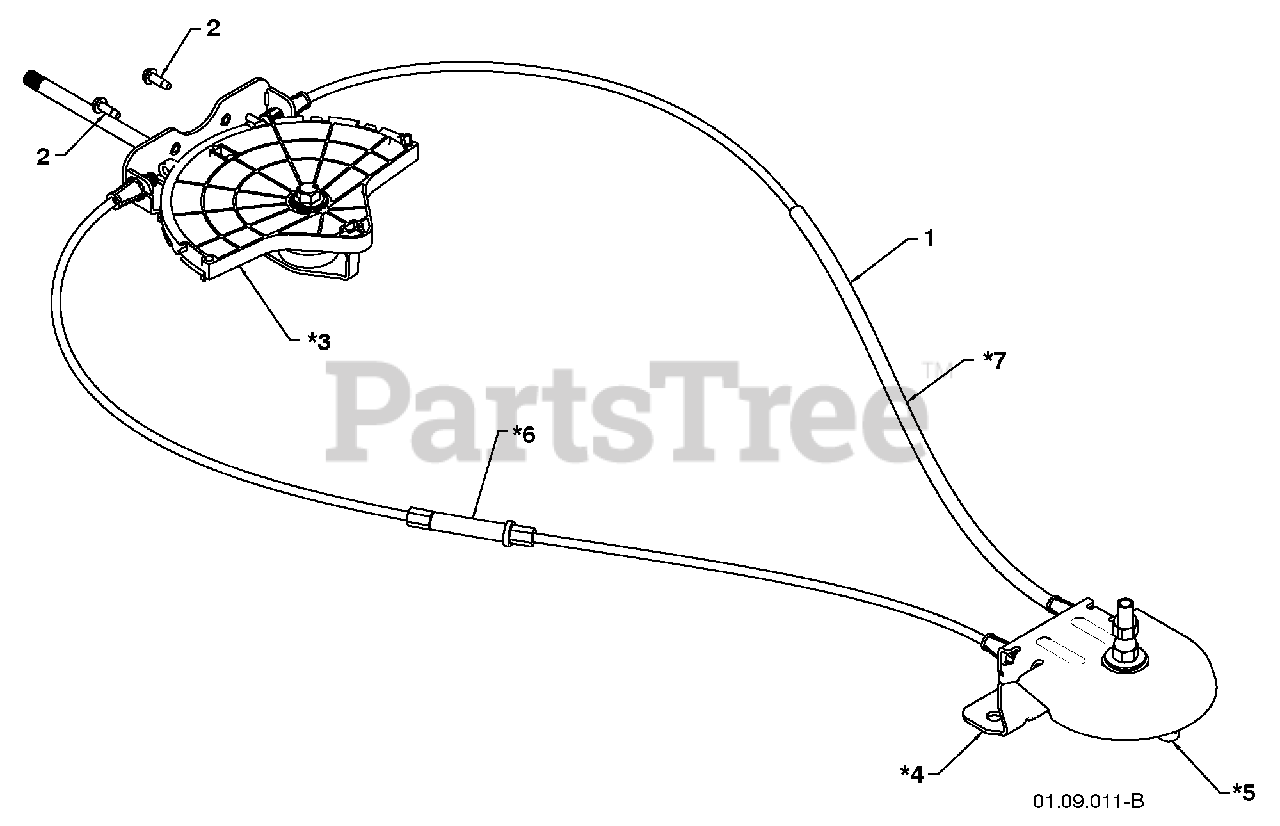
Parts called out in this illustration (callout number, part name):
1	LEVER/CABLE ROTATOR ASSEMBLY
2	SCREW 10-24 X .625
3	ROTATOR HEAD
4	ROTATOR PIVOT BRACKET
5	PULLEY PIVOT
6	CABLE ASSEMBLY ADJUSTABLE GRAY
7	CABLE ASSEMBLY HEAT SHIELD GRAY
